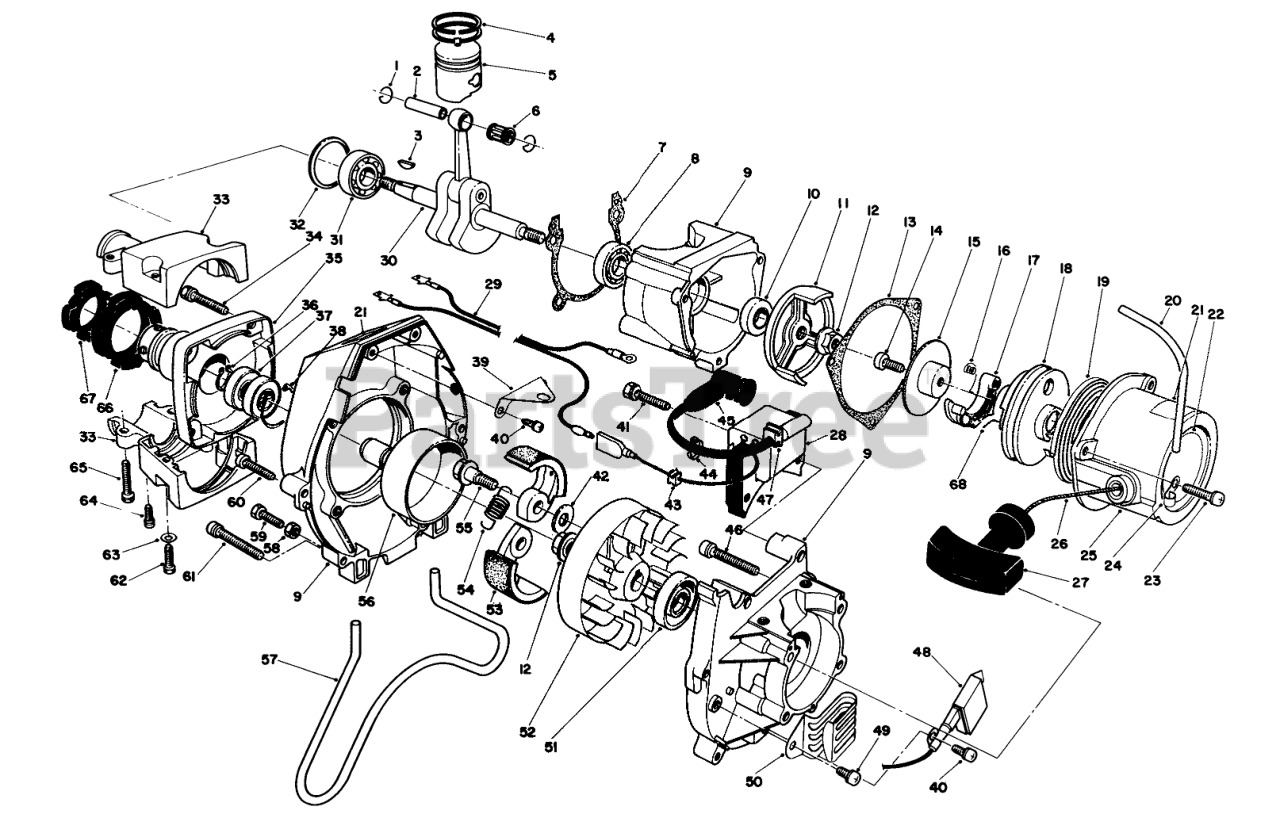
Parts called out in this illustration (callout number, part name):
1	PISTON PIN CLIP
2	PISTON PIN
4	PISTON RING
5	Piston Set (Incl. Ref. #2)
6	NEEDLE BEARING
7	Gasket-Case
8	BEARING
9	Crankcase (Inch Ref. #46 & 59)
10	OIL SEAL
11	PULLEY, STARTER
13	Gasket-Starter
14	Screw
15	PLATE, FRICTION
16	SPRING, RETURN
17	RATCHET
19	SPRING, SPIRAL
20	PIPE, OVERFLOW
21	DECAL HOT
22	Decal
23	Screw
24	Clamp
25	Recoil Starter (Incl. Ref. #11, 14-19, 26, 27, & 67)
26	Rope-Recoil
27	Knob-Starter
28	IGNITION COIL
29	Lead-Wire
30	Crankshaft (Incl. Ref. #3, & 6)
31	BALL BEARING
32	SNAPRING
33	Holder
34	Bolt/Washer
35	Case-Clutch
36	SNAP RING
37	BALL BEARING
38	SNAP RING
39	Bracket
40	SCREW W/ WASHER
41	BOLT AND WASHER
42	Washer
43	Grommet
45	CAP-PLUG
46	SCREW & WASHER
47	Grommet
48	UNIT,TRANSISTOR
49	Screw & Washer
50	Clamp
51	OIL SEAL
52	Flywheel
53	SHOE, CLUTCH
54	Spring
55	Bolt-Clutch
56	Drum-Clutch
57	TANK GUARD
60	Screw
61	Screw
63	Washer
64	SCREW & WASHER
65	BOLT-WASHER/ENG
66	RUBBER, CUSHION (A)
67	RUBBER, CUSHION (B)
68	SPRING, FRICTION
